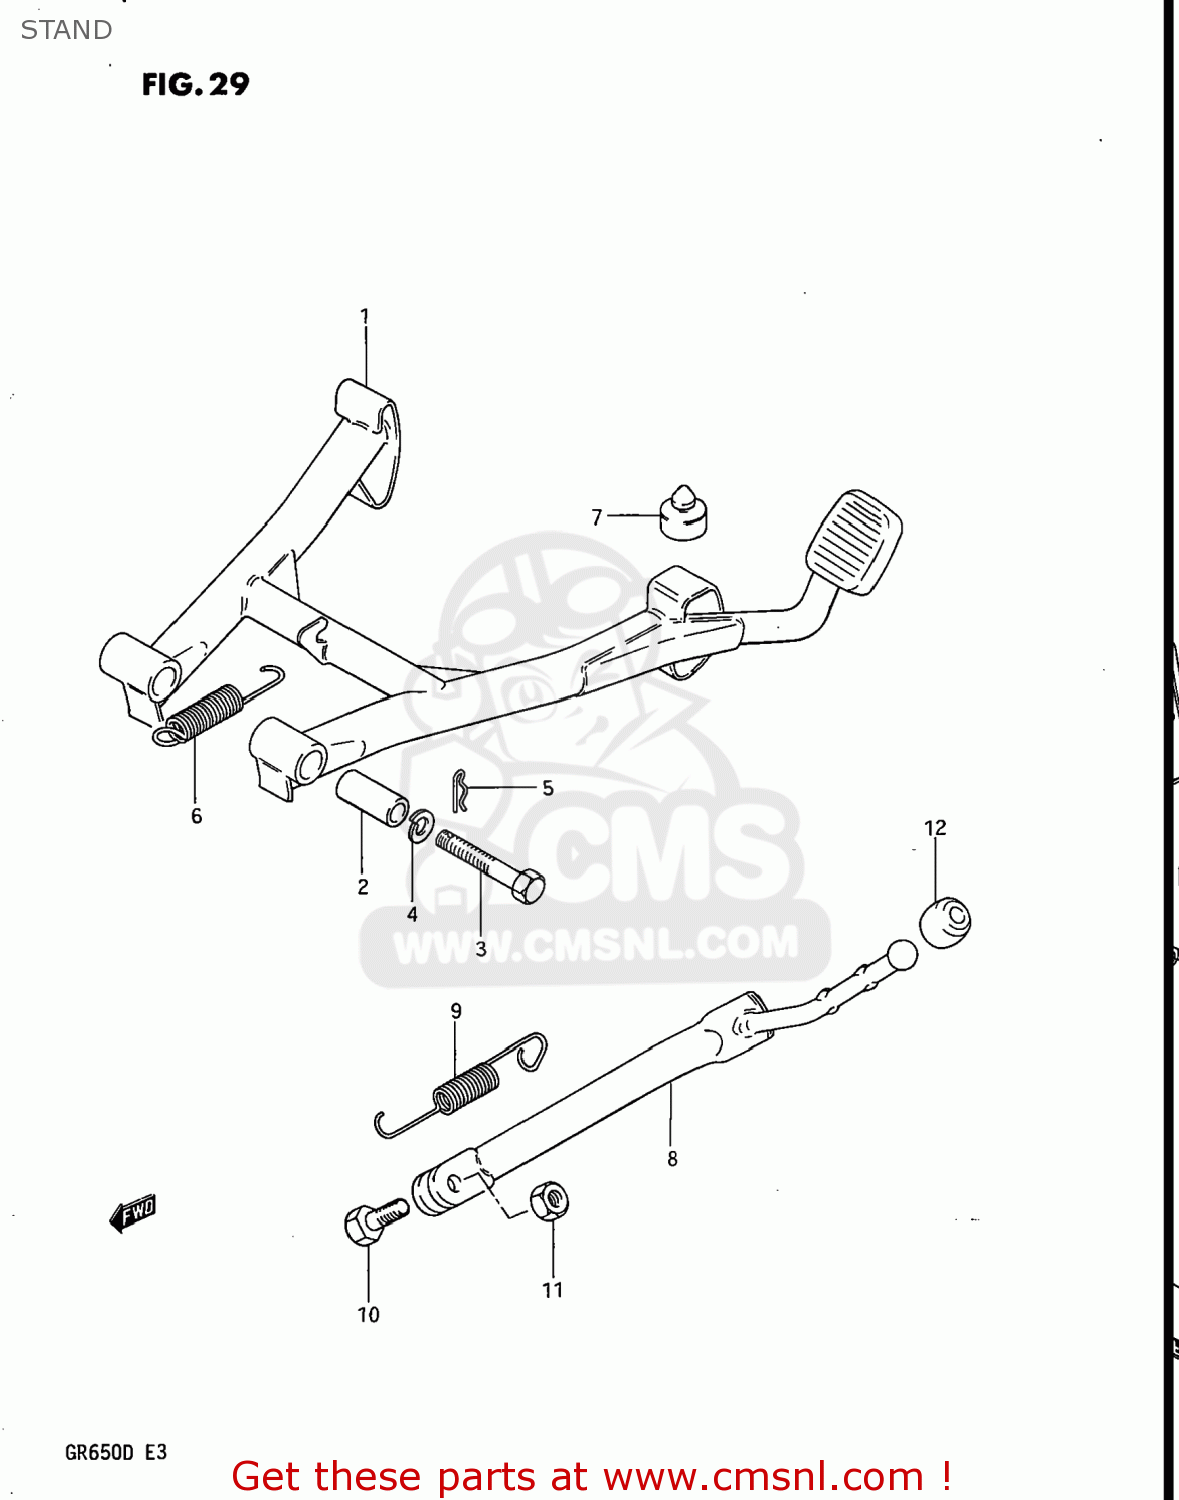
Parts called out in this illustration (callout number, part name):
1	STAND,CENTER
2	SPACER(10X16X38.8)
3	BOLT
4	LOCK WASHER
5	CLIP
6	SPRING
7	CUSHION
8	STAND,SIDE
9	SPRING
10	BOLT L:30
11	NUT
12	CUSHION
